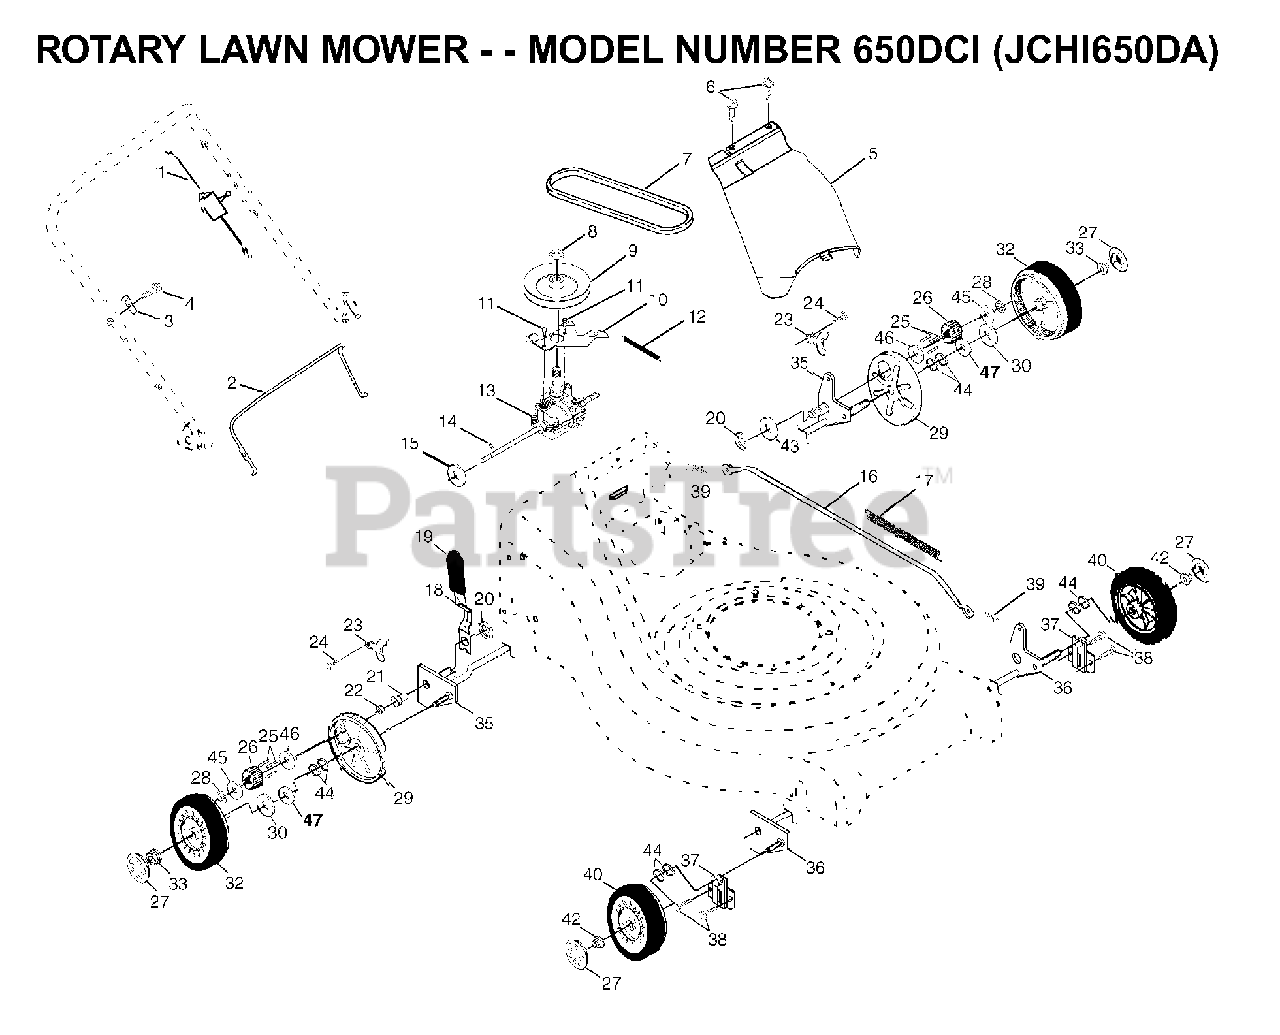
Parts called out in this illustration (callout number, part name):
1	CABLE DRIVE
2	BAIL.CONT.DR.21.RWGD.BLACK
3	DOWNSTOP BRACKET
4	SCREW.HEX.HEAD.WASHER.10-16
5	DRIVE COVER
8	FLANGED LOCKNUT 3/8-16 ZINC
13	TRANSMISSION ASM. (WALK)
14	PIN.SPRING.THRUST
15	THRUST WASHER
16	ROD CONNECTING
17	SPRING
18	SPRING
19	KNOB
21	RP BEARING SUPPORT
22	BEARING, BALL
23	BRACKET
26	DRIVE PINION
27	CAP.HUB.ARC.SPOKE.8".LP
28	E-RING 7/16 RE
29	DUST SHROUD PM
30	WASHER FLUT
33	HEX FLANGE LOCKNT
35	SHAFT ASSY
36	SHAFT ASSY
37	RETAINER.FRONT.SHAFT
39	RETAINER CLIP
40	WHEEL ASMBLY FRONT
42	HEX FLANGE LOCKNT
44	WAVE WASHER
45	WASHER
46	BELLEVILLE WASHER
